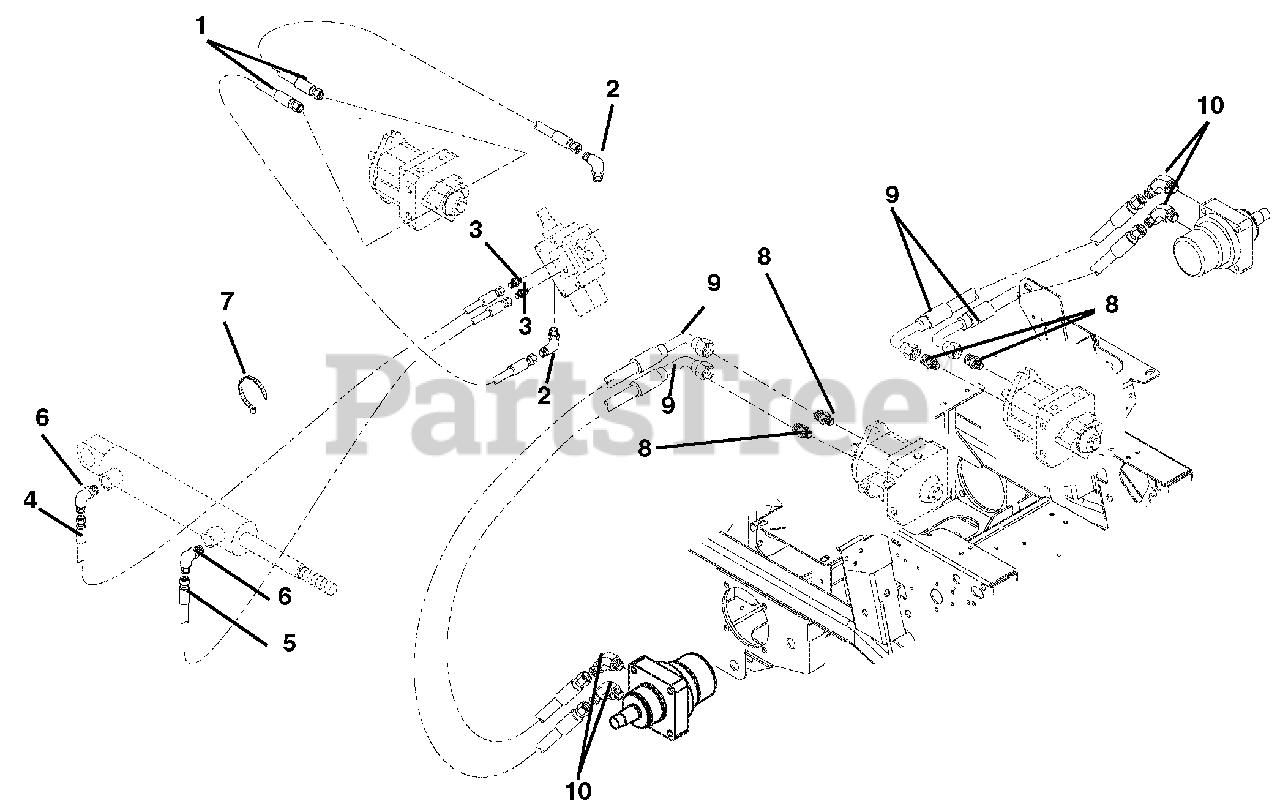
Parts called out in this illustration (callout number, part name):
1	Hose, Hydraulic
2	Fitting, Hydraulic Elbow
4	Hose, Hydraulic
5	Hose, Hydraulic
6	Fitting, Hydraulic
7	Cable Tie
8	Adapter, Face Seal 8 x 8 .50 O-Ring
9	Hose, Hydraulic .50
10	Adapter, Hydraulic Steel .875 to .75
